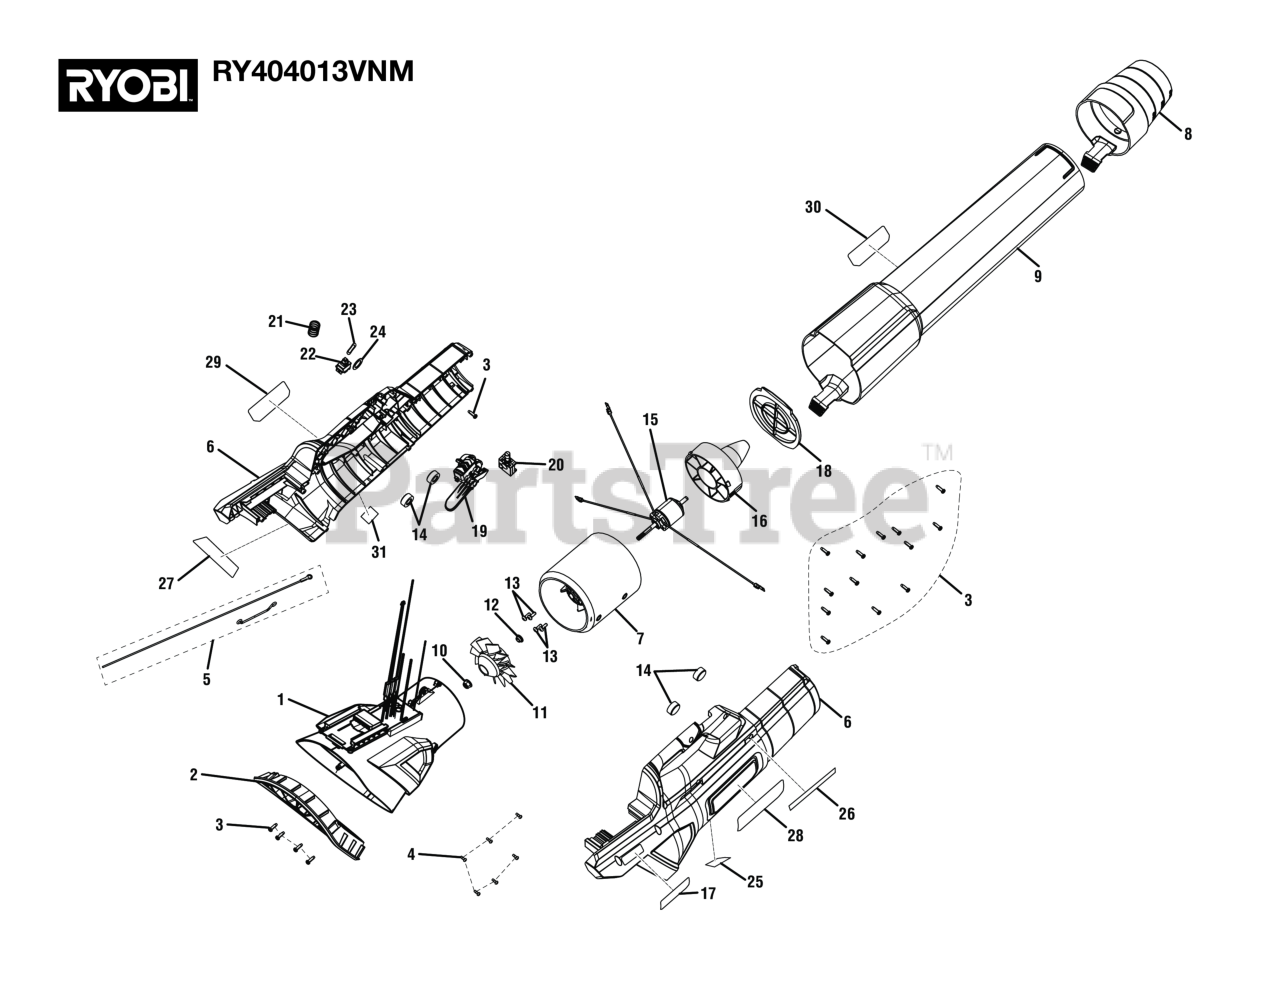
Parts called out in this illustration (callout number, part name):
1	Motor Controller and Inlet Bell Assembly
2	Inlet Guard
3	Screw (M4 x 14 mm, T15 Torx Pan Hd.))
4	Screw (M3 x 8 mm, Pan Hd., Pan Hd)
5	Grounding Strap Assembly
6	Housing Assembly
7	Stator Assembly
8	Speed Nozzle Assembly
9	Blower Tube Assembly (Inc. Key No. 30)
10	Flange Lock Nut (M6 x 1 mm)
13	Screw w/Tooth Washer (M4 x 12 mm, Pan Hd.)
14	Rubber Cap
16	Nose Cone
17	Ingestion Icon Label
18	Cross-Hairs
19	Trigger and Cruise Control Assembly
20	Signal Switch
22	Push Switch
23	Wave Washer
24	Washer (OD21 x 14 x 1t)
26	Icon Label
27	WHISPER SERIES Logo Label
28	Data/Warning Label
29	RYOBI 40V HP Logo Label
30	40V HP BRUSHLESS Logo Label
